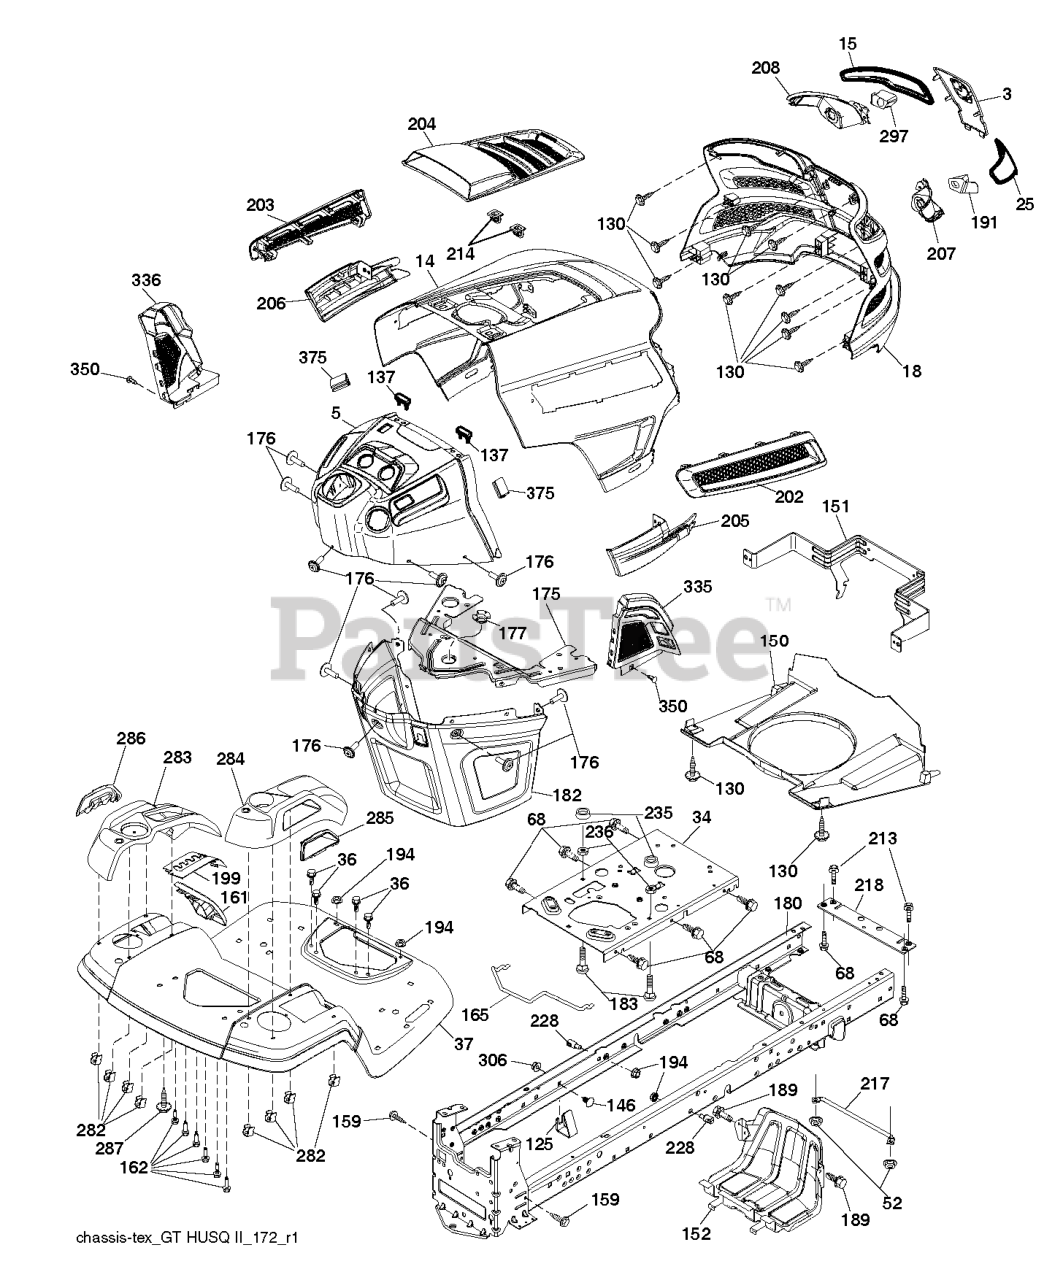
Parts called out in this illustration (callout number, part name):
3	APPLIQUE.SUBASM.GT.HUSQ.II
5	DASH.UPP.GT2.DUAL.RD.PTO.MCHOK
14	HOOD.ASM.HUSQVARNA.GT.TEX.ORAN
15	LENS.HEADLIGHT.LH.GTII.2011
18	GRILLE.SUBSTRATE.2011.
25	LENS.HEADLIGHT.RH.GTII.2011
34	PLATE.ENGINE.WELDED.CHASSIS
36	SCREW 5/16"
37	FENDER.TLT.FS.W/CPH/FW/RSF.668
52	LOCKNUT
68	Screw 5/16-18 x 1/2 Hex, Self Tapping 5/16-18 x 1/2
125	CLIP.FUEL.LINE
130	SCREW.#10 X 0.750.BOS
137	BUMPER DASH
146	BOLT.RDHD.SHT.SQNK.3/8-16X5/8
150	AIR DUCT.GTV2(1.66"RING HEIGHT
151	BRACKET.PIVOT.HOOD.GT.HUSQ.II
152	SHIELD.BROWNING.PNT.GT.V2
159	SCREW, 3/8-16X3/4
161	WINDOW.FUEL.LT.HUSQ.TEX.498
162	SCREW.HI-LO.CONSOLE
165	SUPPORT.TANK.REAR.W/TEX
175	PLATE.CROSSMEMBER.HUSQ
176	SCREW.#10-24X5/8.RN.QU
177	BUSHING STEERING
180	CHASSIS
182	DASH.LOWER.COMMON.12V.ADAPTOR
183	BOLT.5/16-18X1-1/4 FULL THD
189	SCREW
191	INSERT.REFLECTIVE.RH.HUSQ.GTII
194	NUT LOCK HEX FLANGE 5/16-18
199	PLATE.DECK.LIFT.HUSQ.LT
202	VENT.SIDE.RH.GT.HUSQ.II.
203	VENT.SIDE.LH.GT.HUSQ.II.498
204	VENT.TOP.HUSQ.GT2
205	SIDE.TRIM.RH.GT.HUSQ.II
206	SIDE.TRIM.LH.GT.HUSQ.II.GRAY
207	BEZEL LIGHT.RH.GT.II.MYLAR
208	BEZEL LIGHT.LH.GT.II.MYLAR
213	BOLT
214	CLIP.RETAINER.TINNER.
217	ROD.PIVOT.HOOD
218	X-PIECE.HOOD.STOP.NON/
228	STUD.FASTNER.W/ANTI-ROTATE
235	SPACER FENDER
236	NUT.CENTERLOCK.5/16-
282	CLIP.RETAINER.CONSOLE.LT.HUSQ
283	CONSOLE.DECK.LIFT.R.SDFL.HUSQ
284	CONCOLE.CNTRL.PDL.HUSQ.LT.498
285	CONSOLE INSERT RH
286	CONSOLE.INSRT.LH.HUSQ.LT.BLACK
287	SCREW 1/4X20
297	INSERT.REFLECTIVE.LH.HUSQ.GTII
306	NUT LOCK FLG 3/8-16 UNC
335	COVER.LOWER.DASH.RH.BLACK
336	COVER-LH.LOWER.DASH.GT2.BLACK
350	CLIP.X-MAS.TREE
375	BUMPER CLIP-ON. DASH 1"
